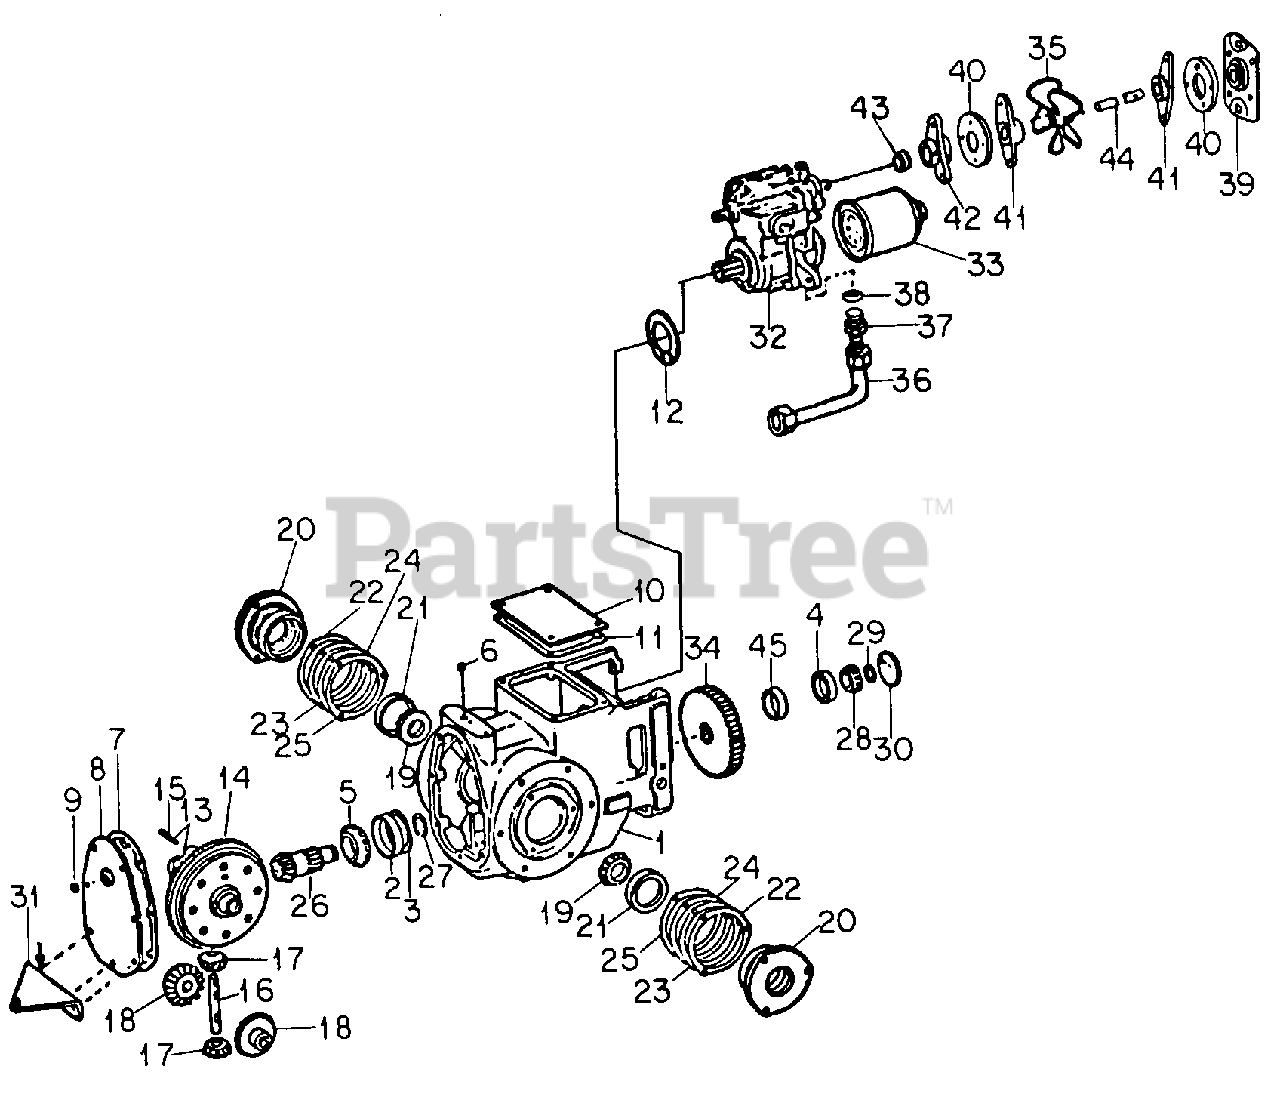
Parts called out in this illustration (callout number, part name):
1	Case Assy, Transmission
2	Bearing, Bevel Pinion Shaft Rear Cup
3	Shim, Rear Brg Cup, .004
4	Bearing, Bevel Pinion Shaft Front Cup
5	Bearing, Bevel Pinion Shaft Rear Cone
6	Plug, Breather
7	Gasket, Rear Cover Plate
8	Plate Assy, Rear Cover
9	Plug, 1/2-14 Auto Sq Soc Hd Drain
10	Cover Assy, Trans. Case
11	Gasket, Top Cover
12	Gasket, Front
13	Case w/Drive Gear, Differential
14	Gear, Drive -46T
15	Pin, Pinion Shaft Lock
16	Shaft, Pinion
17	Pinion, -10T
18	Gear, Side
19	Bearing, Cone
20	Cage Assy, Differential Brg
21	Bearing, Cup
22	Shim, Brg Retainer, .004
23	Shim, Brg Retainer, .007
24	Shim, Brg Retainer, .0149
25	Shim, Brg Retainer, .0299
26	Shaft, Bevel Pinion
27	Ring, Gear Ret
28	Bearing, Bevel Pinion Shaft Frt Cone
29	Ring, Pinion Shaft Frt Brg Ret, .125
30	Plug, 2-1/8 Expansion
31	Drawbar, Fixed
32	Transmission Assy, Hydrostatic Drive
33	Filter
34	Gear, Constant Mesh -68T
35	Fan, Cooling
36	Tube Assy, Transmission
37	Connector, 37 Deg Hyd Flared Swivel
38	O-Ring, 5/8 OD Tube
39	Flange, Drive Shaft
40	Disc, Flexible Coupling
41	Arm, Coupling
42	Coupling, Drive Shaft
43	Bushing, Self-Aligning Ball
44	Shaft, Drive
45	Spacer, Pinion Shaft Gear
